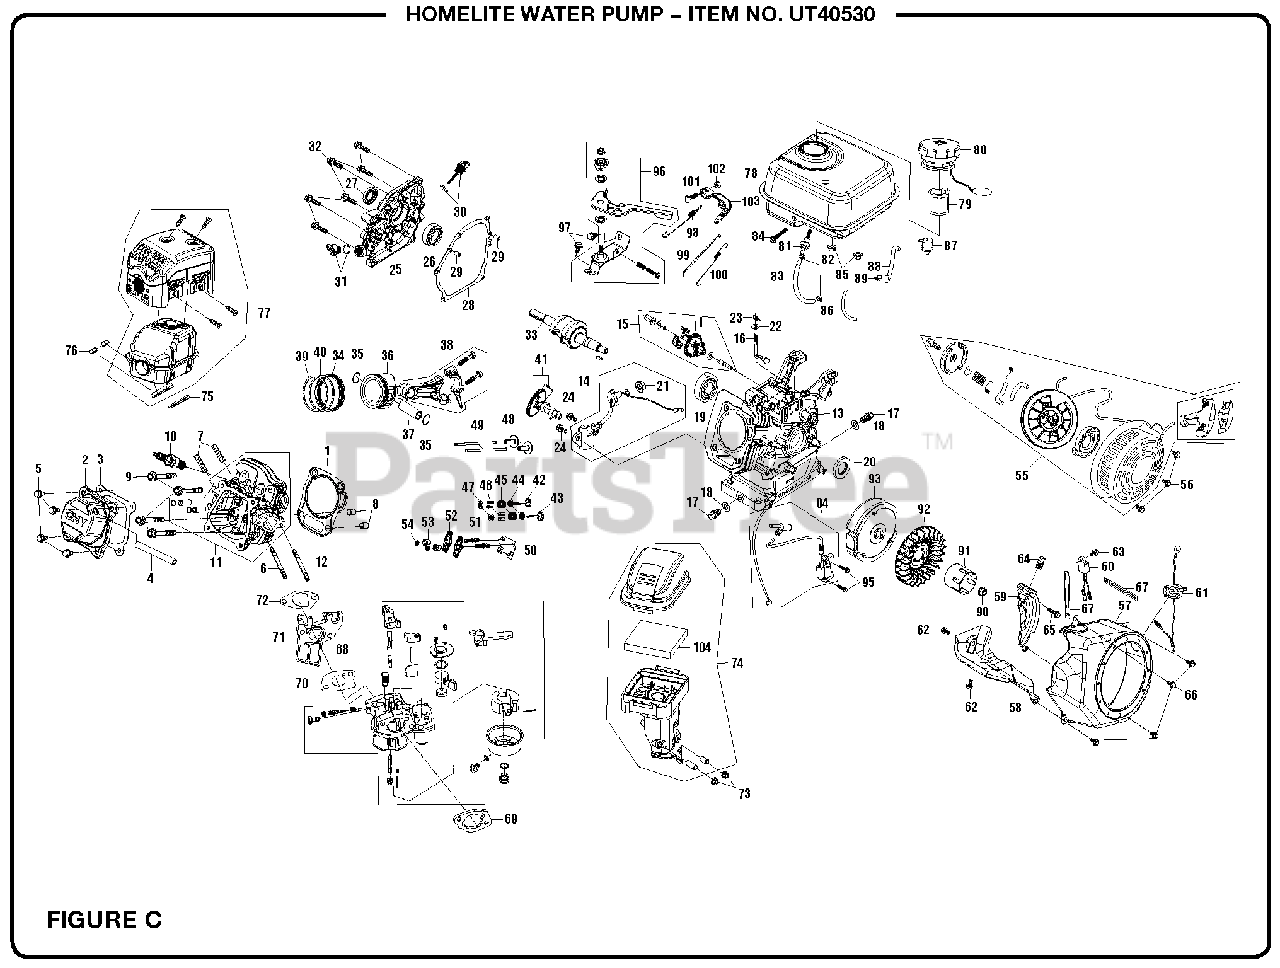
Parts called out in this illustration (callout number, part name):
1	Cylinder Head Gasket
2	Cylinder Head Cover Assembly
3	Cylinder Head Cover Gasket
9	Cylinder Head Bolt
11	Cylinder Head Assembly
13	Crankcase Assembly
14	Engine Oil Sensor
15	Governor Gear Assembly
17	Drain Plug Bolt
19	Ball Bearing
22	Governor Gear Washer
25	Crankcase Cover Assembly
26	Ball Bearing
28	Crankcase Gasket
30	Oil Dipstick Assembly
31	Engine Oil Plug Assembly
33	Crankshaft Assembly
35	Piston Pin Clip
36	Piston Assembly
40	The Second Ring
41	Camshaft Assembly
42	Exhaust Valve
43	Intake Valve
46	Valve Lock Clip
47	Valve Spring Seat
50	Lifter Stopper Plate Assembly
51	Valve Adjusting Bolt
53	Valve Adjusting Nut
55	Recoil Starter Assembly
58	Cylinder Body Shroud
61	Stop Engine Switch Assembly
68	Carburetor Assembly
69	Air Cleaner Gasket
70	Carburetor Gasket
71	Carburetor Insulator Plate
72	Carburetor Insulator Gasket
75	Exhaust Outlet Gasket
77	Muffler Assembly
80	Fuel Tank Cover
81	Fuel Tank Oil Outlet Assembly
88	Fuel Steam Rubber Hose
93	Flywheel Assembly
96	Throttle Control Assembly
98	Governor Spring
100	Throttle Valve Return Spring
101	Governor Support Bolt
103	Governor Support Assembly
104	Air Cleaner Element
